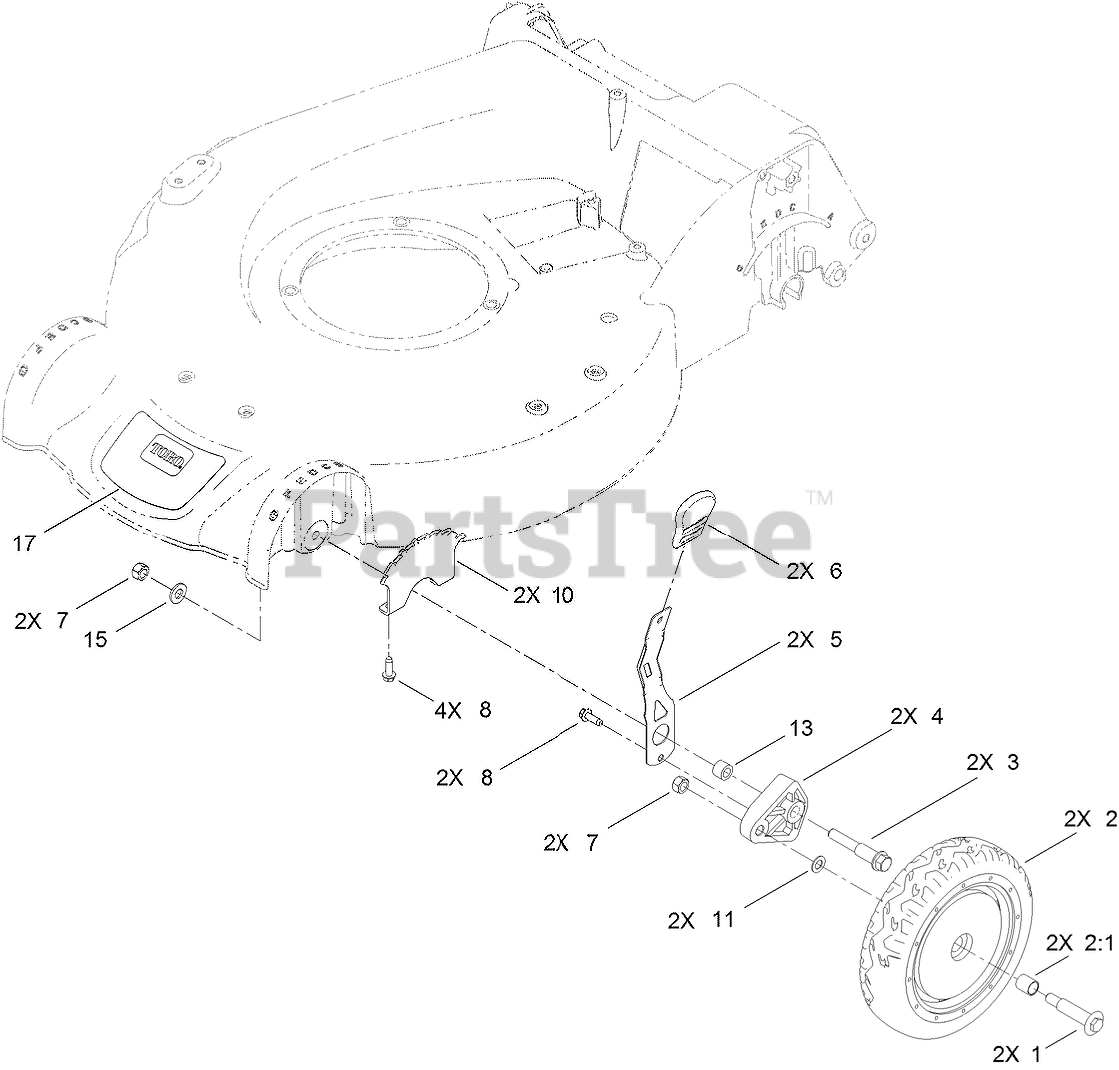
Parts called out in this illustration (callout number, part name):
1	BOLT-SHOULDER
2	WHEEL ASM
2:1	BUSHING
3	SCREW-SHOULDER
4	ARM-PIVOT
5	ARM-SPRING
6	KNOB-HOC
8	SCREW-HWHTF
10	PLATE-HOC
11	WASHER
13	SPACER-WHEEL
15	WASHER-FLAT
17	DECAL-HOUSING
